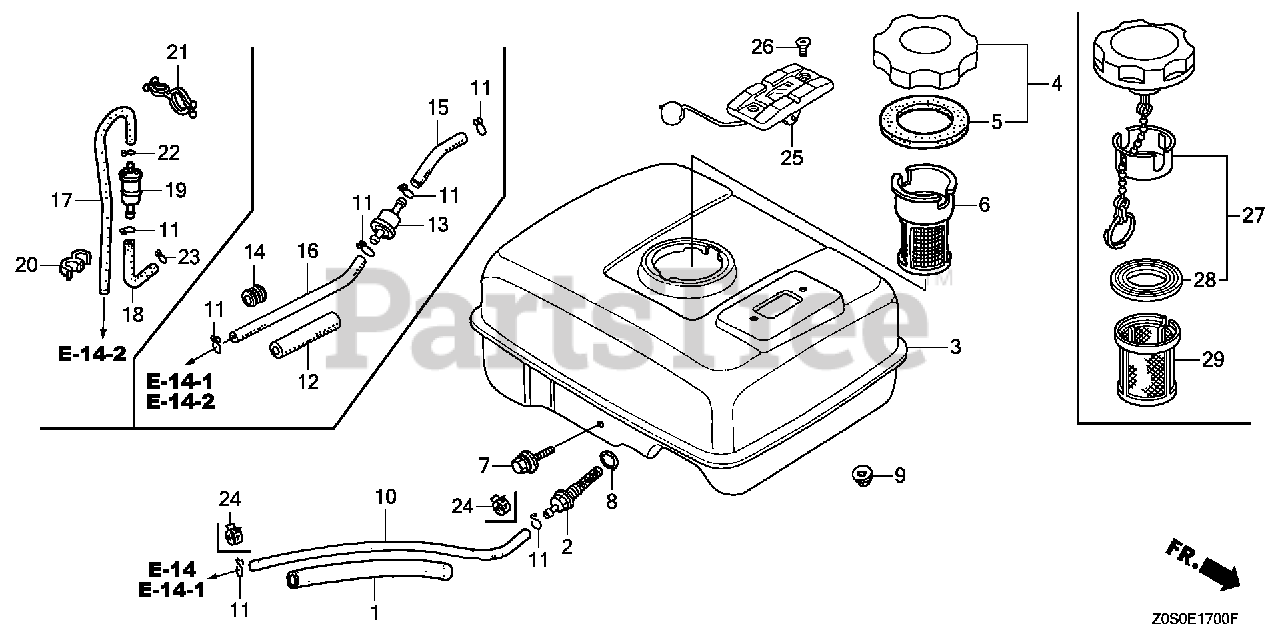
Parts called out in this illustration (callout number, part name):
1	RUBBER, SUPPORTER (107MM)
2	JOINT, FUEL TANK
3	TANK, FUEL *NH1* (BLACK)
3	TANK, FUEL *NH31* (MCKINLEY WHITE)
4	CAP, FUEL FILLER (CHROME PLATED)(RADICON)
4	CAP, FUEL FILLER (CHROME PLATED)(TOUYOUSYA)
5	GASKET, FUEL FILLER CAP
5	GASKET, FUEL FILLER CAP (39X62X3) (TOUYOUSYA)
7	BOLT, FLANGE (6X29)
8	O-RING (14MM) (ARAI) Use up to Engine SN 2949254.
8	O-RING (14MM) (NOK)
9	NUT, FLANGE (6MM)
10	BULK HOSE, FUEL (4.5X3000) (Honda Code 5137104). (4.5X140)
11	CLIP, TUBE (B8)
